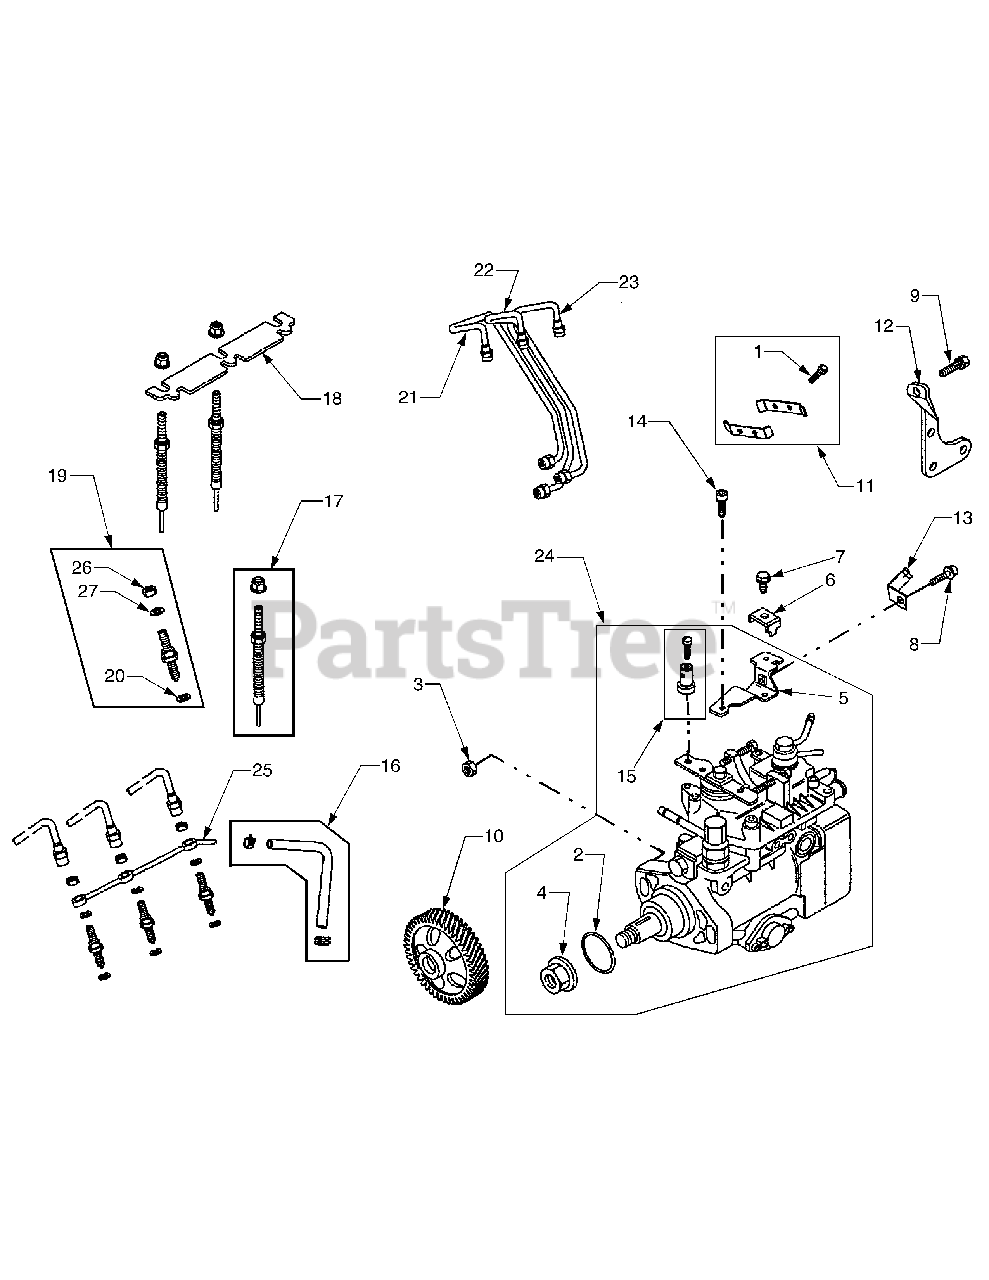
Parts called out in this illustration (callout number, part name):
1	Screw, Hex, 6mm
2	Seal, O-Ring
3	Nut, Hex Metric
4	Nut, Hex Metric
5	Bracket, Casing Clamp
6	Clamp, Casing
7	Screw, Casing Clamp
8	Screw, Support Bracket
9	Screw, Support Bracket
10	Gear, Drive
12	Bracket, Support
13	Bracket, Support
14	Screw, Casing Clamp Bracket
15	Clamp, Swivel
16	Hose/Clamp Ass’y., Fuel Return
17	Plug, Glow
18	Strap, Glow Plug
19	Nozzle, Injector
20	Seat, Injector
21	Pipe, Injector #1
22	Pipe, Injector #2
23	Pipe, Injector #3
24	Pump, Injection
25	Pipe, Fuel Return
26	Nut, Hex Injector Nozzle
27	Washer, Injector Nozzle
